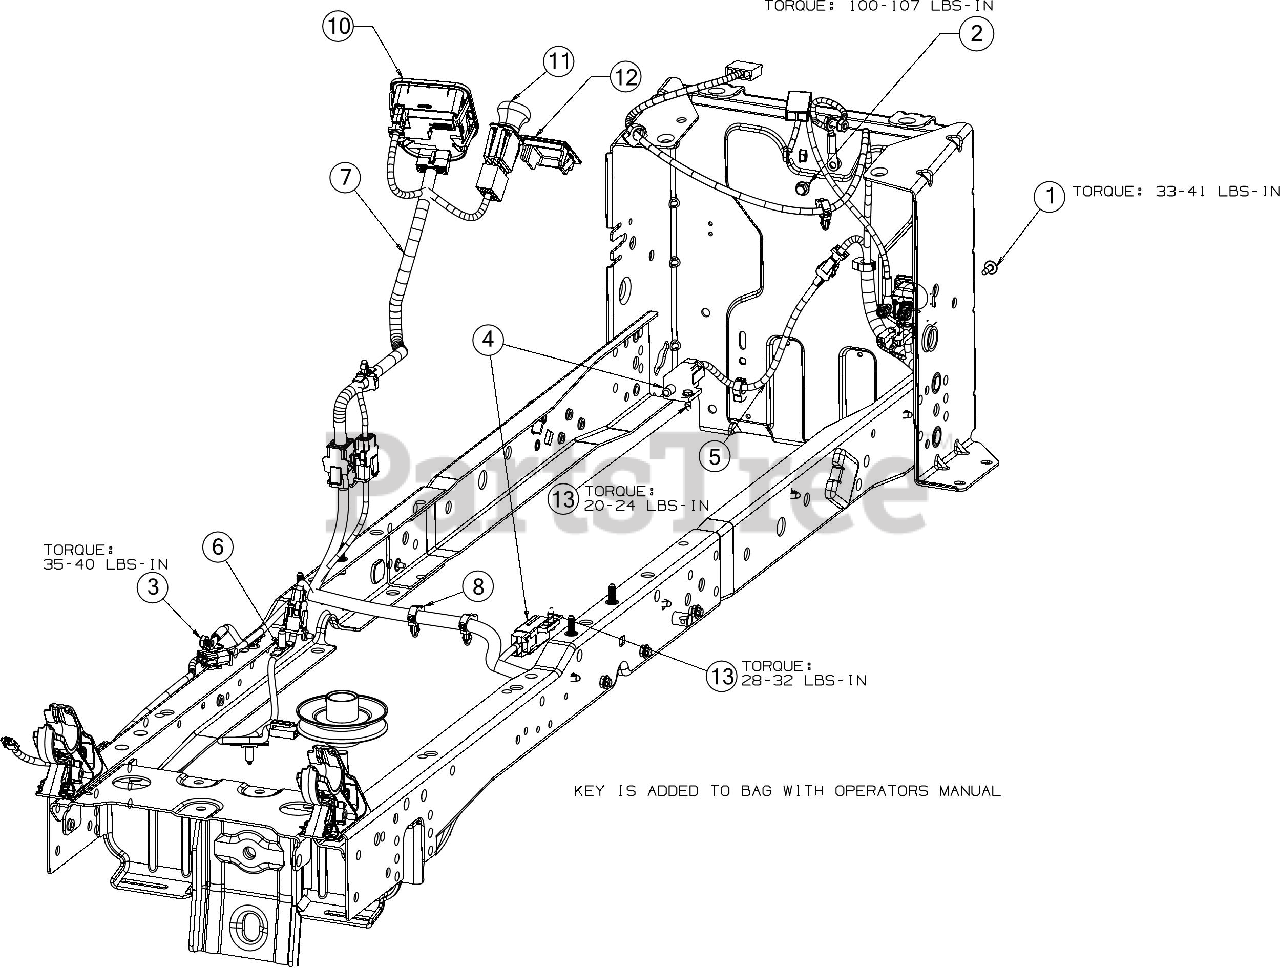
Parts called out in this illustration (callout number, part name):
1	SCREW M6-1 x .625
2	SCREW 1/4-20X.625
3	HEX NUT 1/4-20
4	INTERLOCK SWITCH (NO/NC)
5	REVERSE HARNESS
6	CLUTCH HARNESS 11"
7	MAIN HARNESS E-PTO/PBS/RMC
8	DASH HARNESS E-PTO/PBS/RMC
10	MODULE-PBS/HRMTR/SVC MNDR/BT
11	PTO SWITCH (YELLOW KNOB)
12	DASH HOUR METER PLUG
13	SHOULDER SCREW
